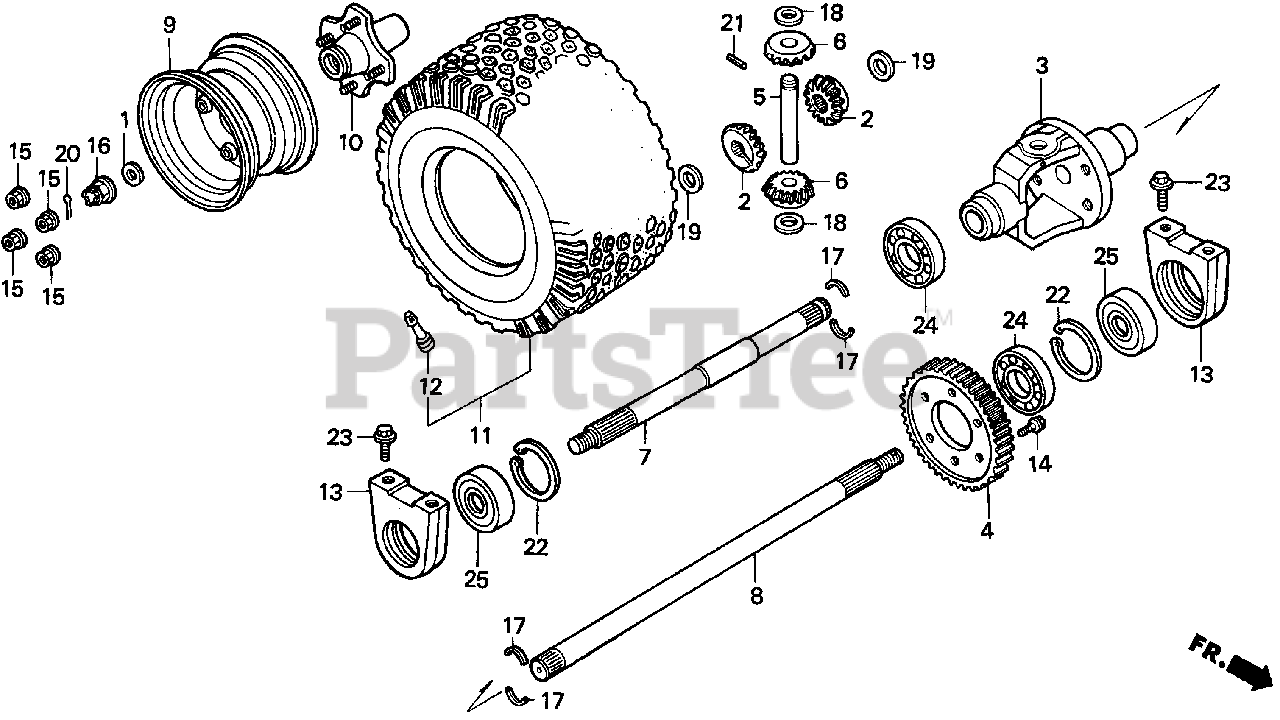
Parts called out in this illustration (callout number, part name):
1	WASHER (26MM) (SOURCE: VINTAGE PARTS INC.)
2	GEAR, DIFFERENTIAL
3	CASE, DIFFERENTIAL GEAR
4	GEAR, FINAL DRIVEN (59T)
5	SHAFT, DIFFERENTIAL
6	PINION, DIFFERENTIAL
7	SHAFT, R. AXLE
8	SHAFT, R. AXLE
9	RIM, WHEEL *NH35M* (CLOUD SILVER METALLIC)
10	HUB, RR. WHEEL
11	TIRE, RR. TUBELESS (16X6.50-8NHS) (GOODYEAR)
12	VALVE, RIM
13	HOLDER, BEARING
14	BOLT, SPECIAL (10X20)
15	NUT, WHEEL (12X1.5)
16	NUT, AXLE (14MM)
17	COTTER (15MM)
18	WASHER A, DIFFERENTIAL PINION (14.2X26X0.7)
18	WASHER B, DIFFERENTIAL PINION (14.2X26X0.8)
18	WASHER C, DIFFERENTIAL PINION (14.2X26X0.9)
18	WASHER D, DIFFERENTIAL PINION (14.2X26X1.0)
19	WASHER, DIFFERENTIAL GEAR
20	PIN, SPLIT (3.0X25)
20	PIN, COTTER (3.0X45)
21	PIN, SPRING (4X32)
22	CIRCLIP (INNER) (47MM)
23	BOLT, FLANGE (10X16)
25	BEARING, RADIAL BALL (6204UU)
